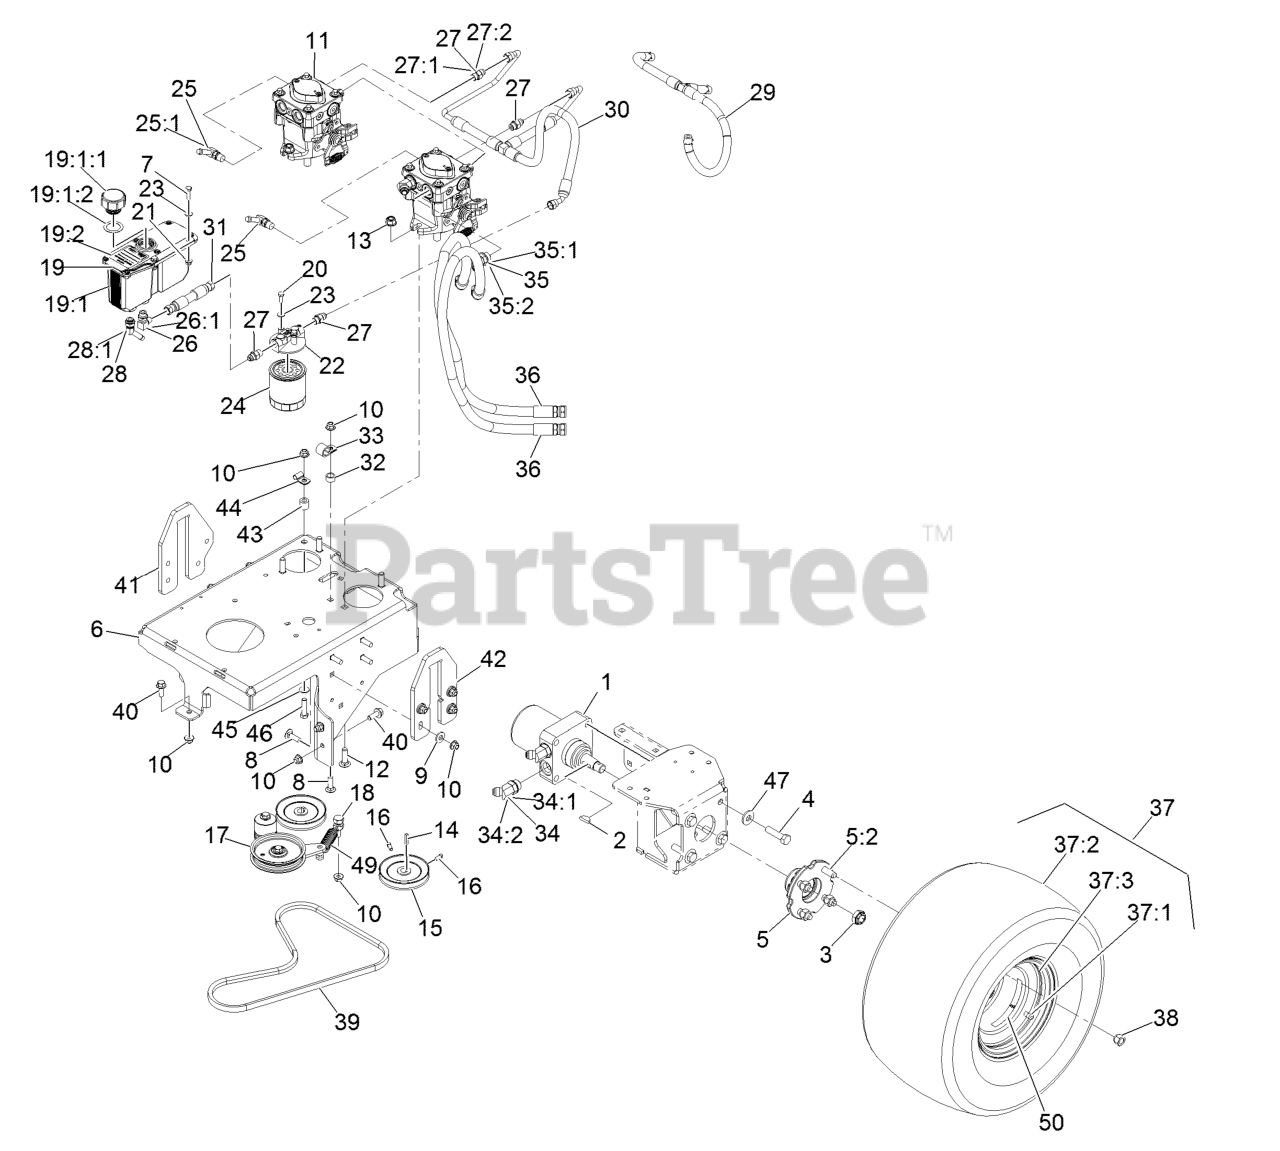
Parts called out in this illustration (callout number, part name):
1	MOTOR-WHEEL
2	KEY-WOODRUFF
3	NUT-LOCK
4	SCREW-HH
5	WHEEL HUB ASM
5:2	STUD-TYPE, DRIVE
6	BASE, ENGINE
7	SCREW-HH
8	BOLT-CARR
9	WASHER-BELLEVILLE
10	NUT-HF, NI
11	PUMP - HYDRAULIC
12	SCREW-HH
13	NUT-HF, NI
15	PULLEY-PUMP
16	SCREW-SET
17	PUMP IDLER ASM
18	ANCHOR, SPRING
19	RESERVOIR ASM
19:1	Reservoir-Hyd
19:1:1	Cap-Reservoir, HYD
19:1:2	GASKET-CAP
19:2	DECAL-HYDRAULIC TANK
20	SCREW-HH
21	NUT-HHF
22	HEAD-FILTER
23	WASHER-FLAT
24	FILTER-25 MICRON, BI-DIRE
25	FITTING-ELBOW, 90
25:1	O-RING
26	FITTING-ELBOW, 90 DEG
27	FITTING-STRAIGHT
28	FITTING-BARBED, 45 DEG
28:1	O-RING
29	TANK HOSE ASM
30	HOSE ASSEMBLY - CHARGE
31	HYD HOSE ASM
32	SPACER-WHEEL
33	CLIP-LOOM
34	FITTING-HYD, 45 DEG
35	FITTING-HYD, 45 DEG
36	HYD HOSE ASM
37	WHEEL/TIRE ASM
37:1	RIM-8 INCH
37:3	Stem-Valve
38	NUT-LUG
39	BELT-V, LOWER PTO
40	SCREW-HHF 3/8-16 X 1
41	PLATE-LIFT, RH
42	PLATE, LIFT LH
44	CLIP-TUBE
45	WASHER-FLAT
46	SCREW-HH
47	WASHER-SPRING
49	SPRING-EXTENSION
